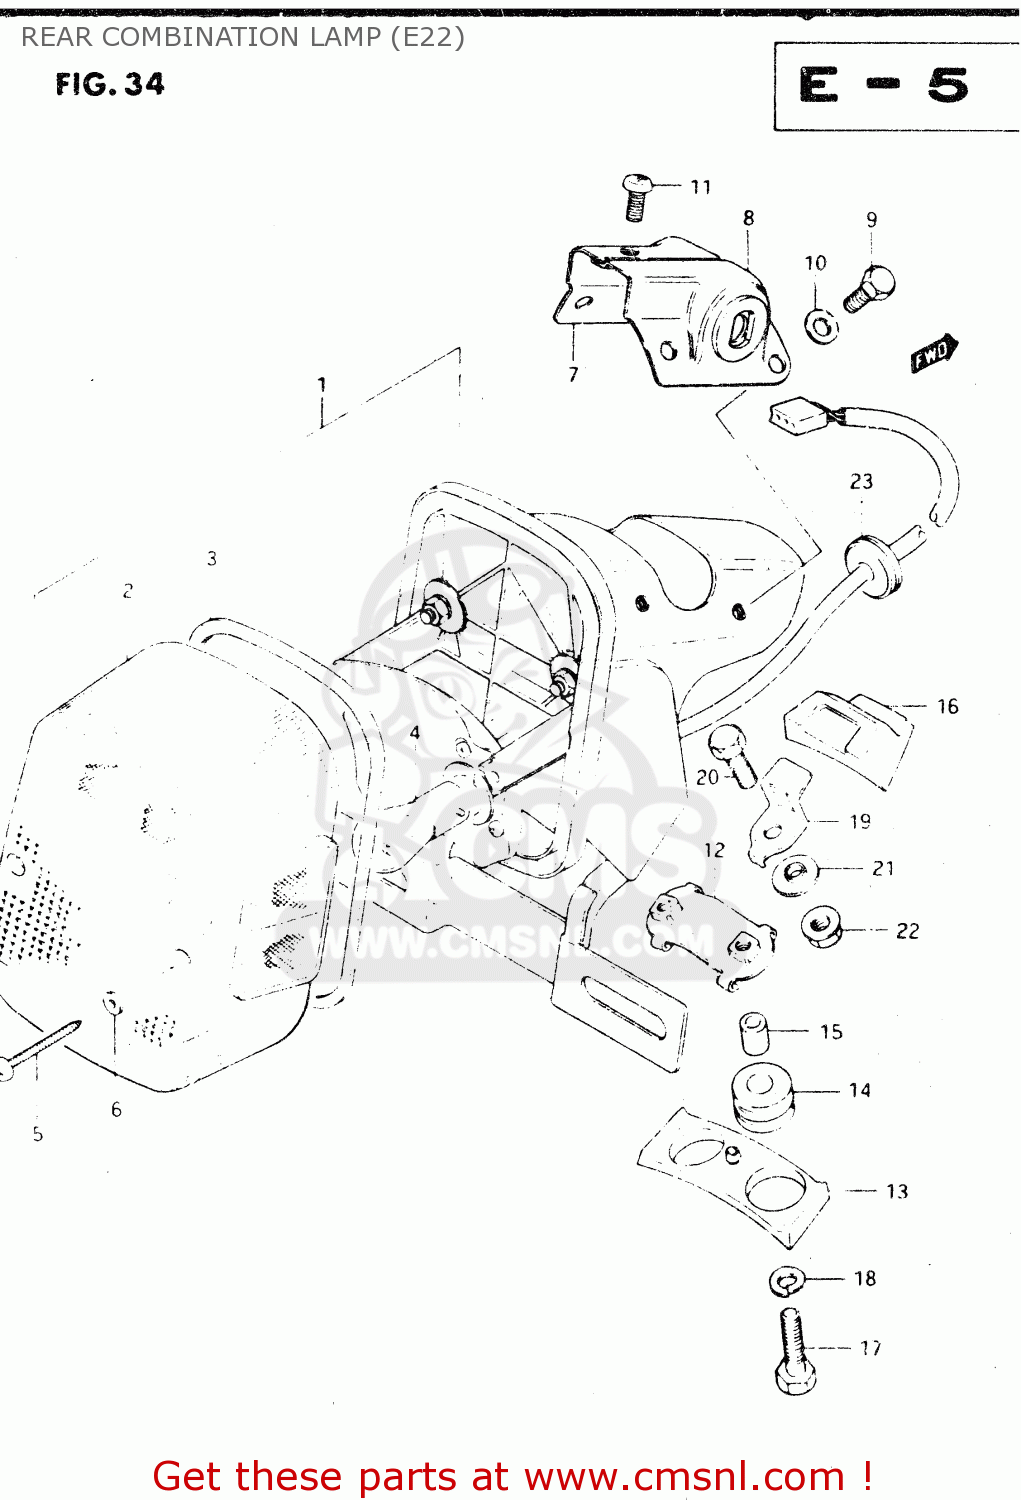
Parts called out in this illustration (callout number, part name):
1	LAMP ASSY, REAR COMBINATION
2	LENS,RR COMBI
3	GASKET (NAS)
4	BULB(12V21/5W)
5	SCREW TAPP.
6	GASKET (NAS)
7	PLATE, RH
8	PLATE, LH
9	BOLT
10	WASHER
11	SCREW
12	PLATE
13	CUSHION
14	CUSHION
15	SPACER
16	CUSHION,REAR COMBINATION LAMP
17	BOLT
18	LOCK WASHER
19	PLATE,RR COMBINATION LAMP
20	BOLT, UPPER
21	WASHER,LOCK
22	NUT
23	GROMMET
